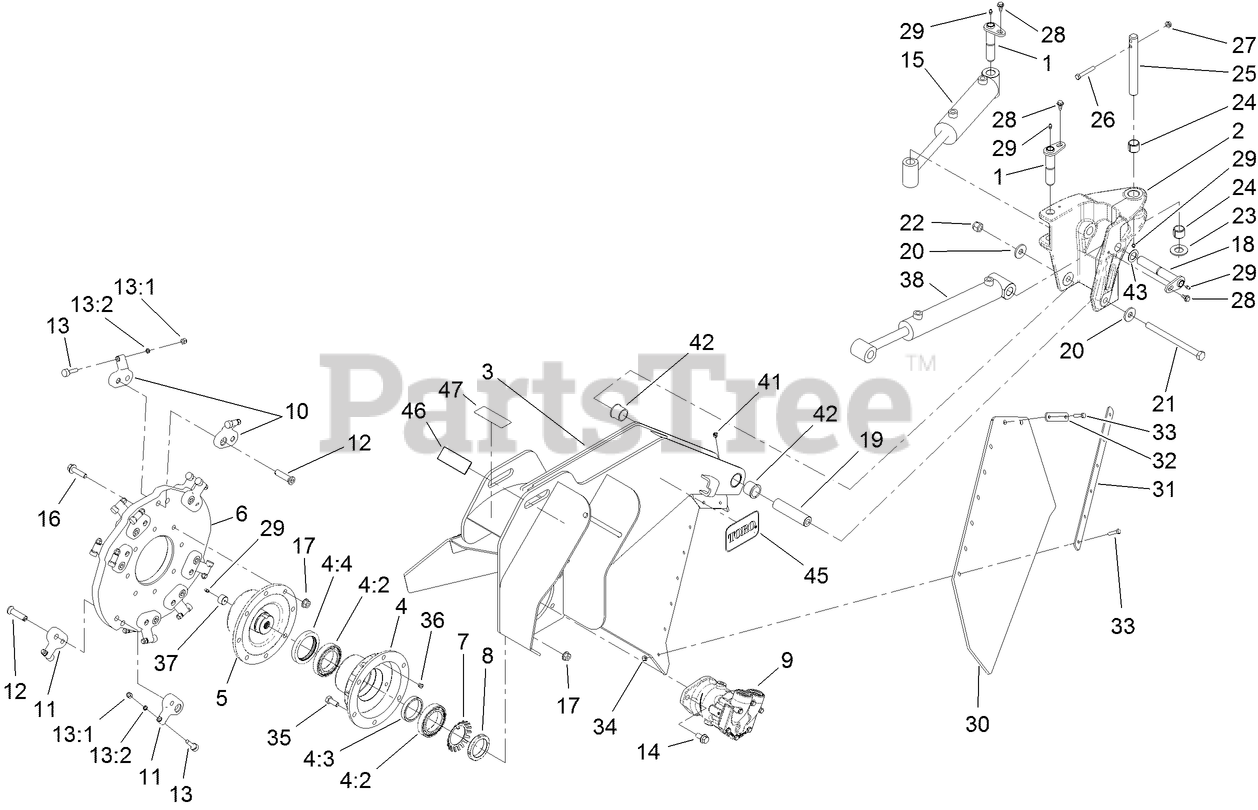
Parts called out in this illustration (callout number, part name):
1	PIN-PIVOT
2	HEAD-PIVOT
3	HEAD-GRINDER
4	WHEEL BEARING HOUSING ASM
4:2	BEARING-BALL
4:3	SPACER-BEARING
4:4	SEAL-GREASE
5	SHAFT-CUTTER
6	PLATE-WHEEL, CUTTER
7	WASHER-LOCK, BEARING
8	NUT-LOCK, BEARING
9	HYD MOTOR ASM
10	POCKET-ANGLED
11	POCKET-STRAIGHT
12	BOLT-HSH
13	GRINDER TOOTH ASM
13:1	NUT-LOCK, NI
13:2	SPACER-TOOTH
14	SCREW-HHF
15	HYD CYLINDER ASM
16	SCREW-HHF
17	NUT-HHF
18	PIN-PIVOT
19	SPACER-PIVOT
20	WASHER-HARDENED
21	BOLT-HH
22	NUT-LOCK, NI
23	WASHER-THRUST
24	BUSHING-TENSION
25	PIN-PIVOT, GRINDER
26	SCREW-HH
27	NUT-HHF, WHIZ
28	BOLT-SHOULDER
29	FITTING-GREASE
30	SHIELD-RUBBER
31	STRAP-RETAINER
32	STRAP-RETAINER
33	SCREW-HH
34	NUT-LOCK, NI
35	SCREW-HH
36	FITTING-LUBE
37	PLUG-SHAFT, CUTTER
38	HYD CYLINDER ASM
41	FITTING-LUBE, 45 DEG
42	BUSHING-FLANGE
43	WASHER-RUBBER
46	DECAL-DANGER
47	DECAL-WARNING
